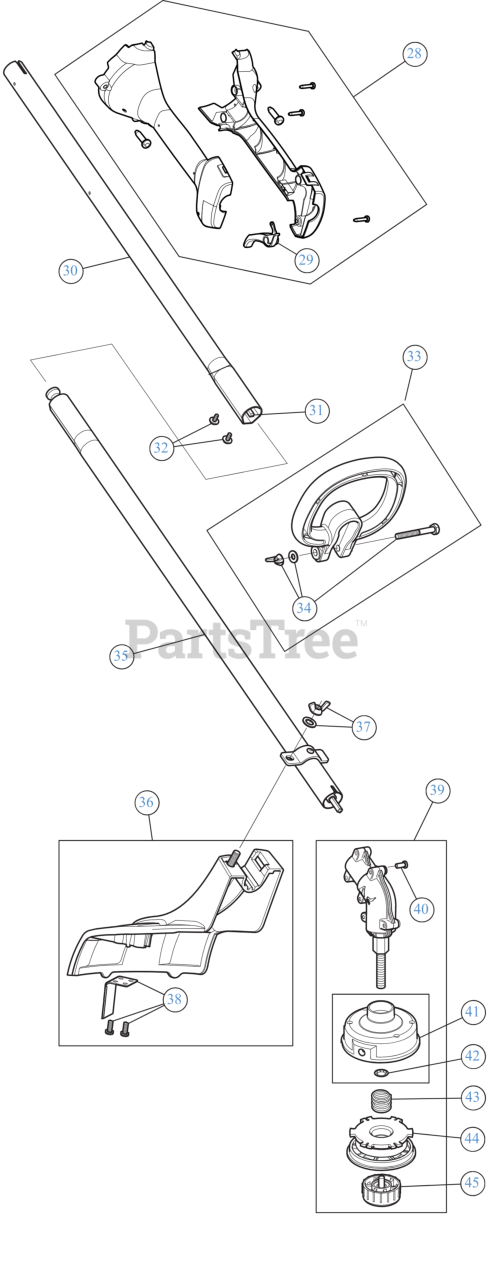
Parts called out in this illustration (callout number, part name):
28	THROTTLE GRIP ASSEMBLY
29	THROTTLE TRIGGER
30	UPPER BOOM ASSEMBLY
31	UPPER SHFT
32	SCREW 8-32X3/8
33	HANDLE
34	HANDLE HWD
35	LOWER BOOM ASSEMBLY
36	GUARD & BLADE ASSEMBLY
37	BLADE GUARD MOUNTING HARDWARE
38	BLADE ASSEMBLY W/HDW
39	GEARBOX ASSEMBLY
40	SCREW 8-32X.437
41	REEL:OTR W/RET
42	RETAINER .625 OD 2
43	SPRING-SPOOL
44	REEL-INNER SPOOL
45	BUMP HEAD KNOB ASSEMBLY
